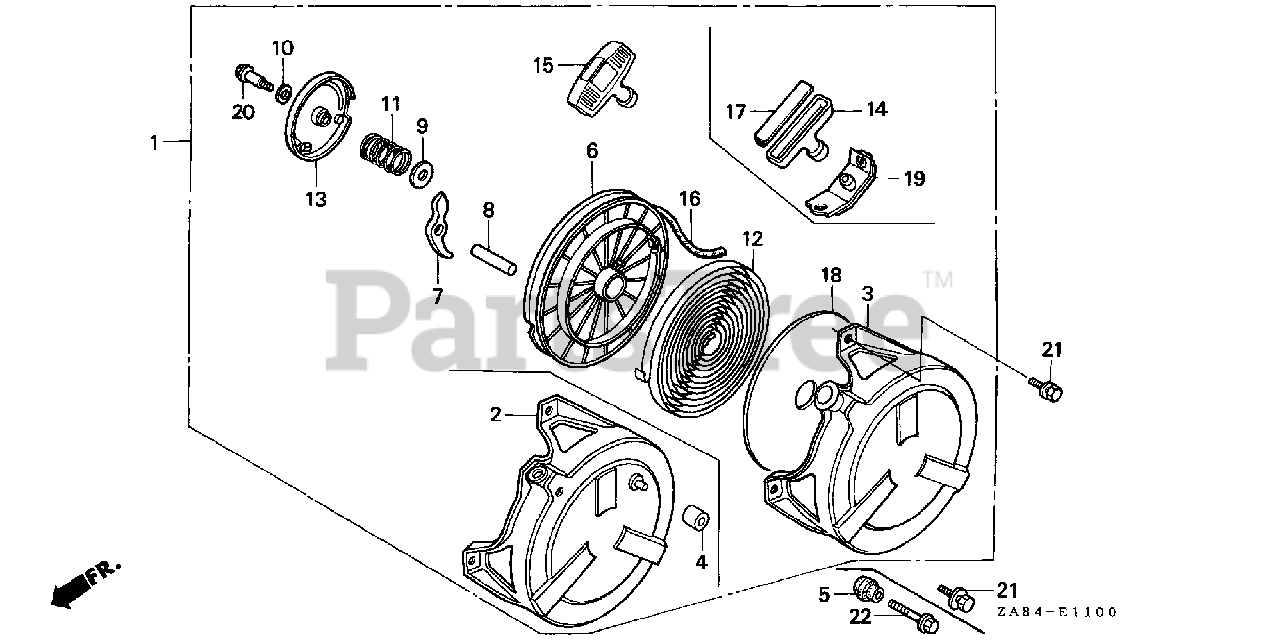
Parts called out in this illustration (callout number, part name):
1	STARTER, RECOIL
1	STARTER ASSY., RECOIL
3	CASE, STARTER
5	STOPPER ASSY., BUMPER
6	REEL, STARTER
7	RATCHET, STARTER
8	SHAFT, RATCHET
9	PLATE A, FRICTION
10	PLATE B, FRICTION
11	SPRING, FRICTION
12	SPRING, RETURN
13	COVER, REEL STARTER
15	GRIP, STARTER
16	ROPE, RECOIL STARTER (#4X55")
16	ROPE, STARTER (#4X65")
16	ROPE (#4X55")
18	PLATE, SIDE
20	BOLT, REEL COVER
21	BOLT-WASHER (6X10)
22	BOLT, FLANGE (6X32)
